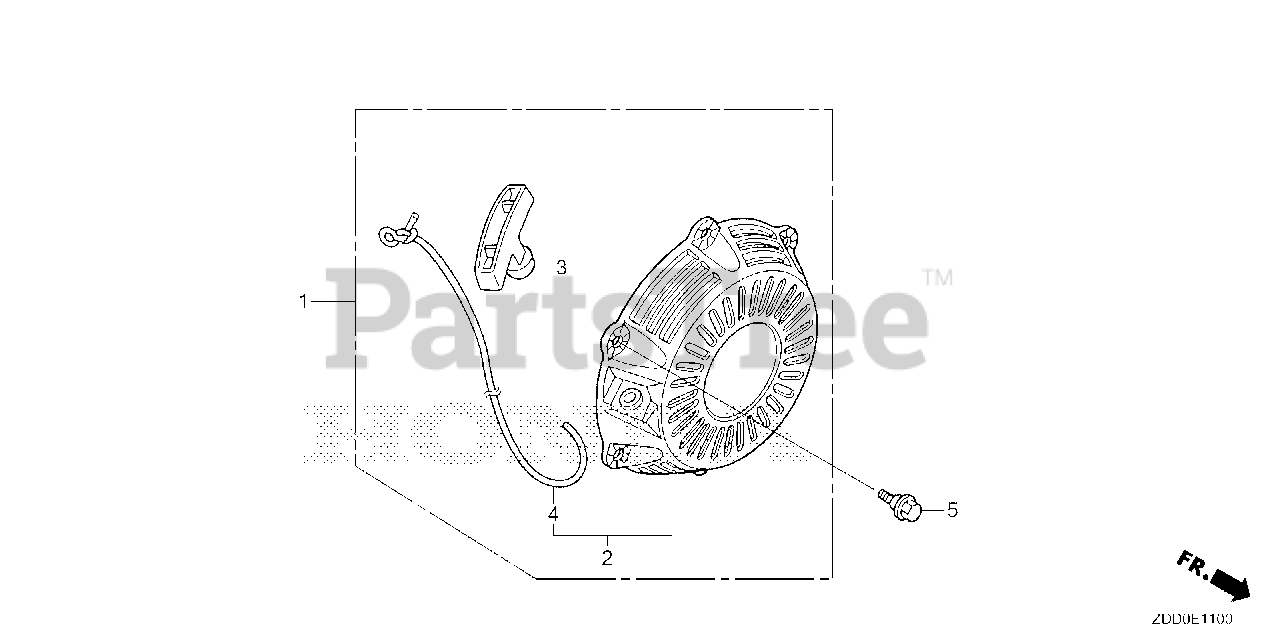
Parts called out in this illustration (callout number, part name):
1	STARTER ASSY., RECOIL *R280* (POWER RED)
3	GRIP, STARTER
4	ROPE, STARTER
5	BOLT, FLANGE (6MM)
